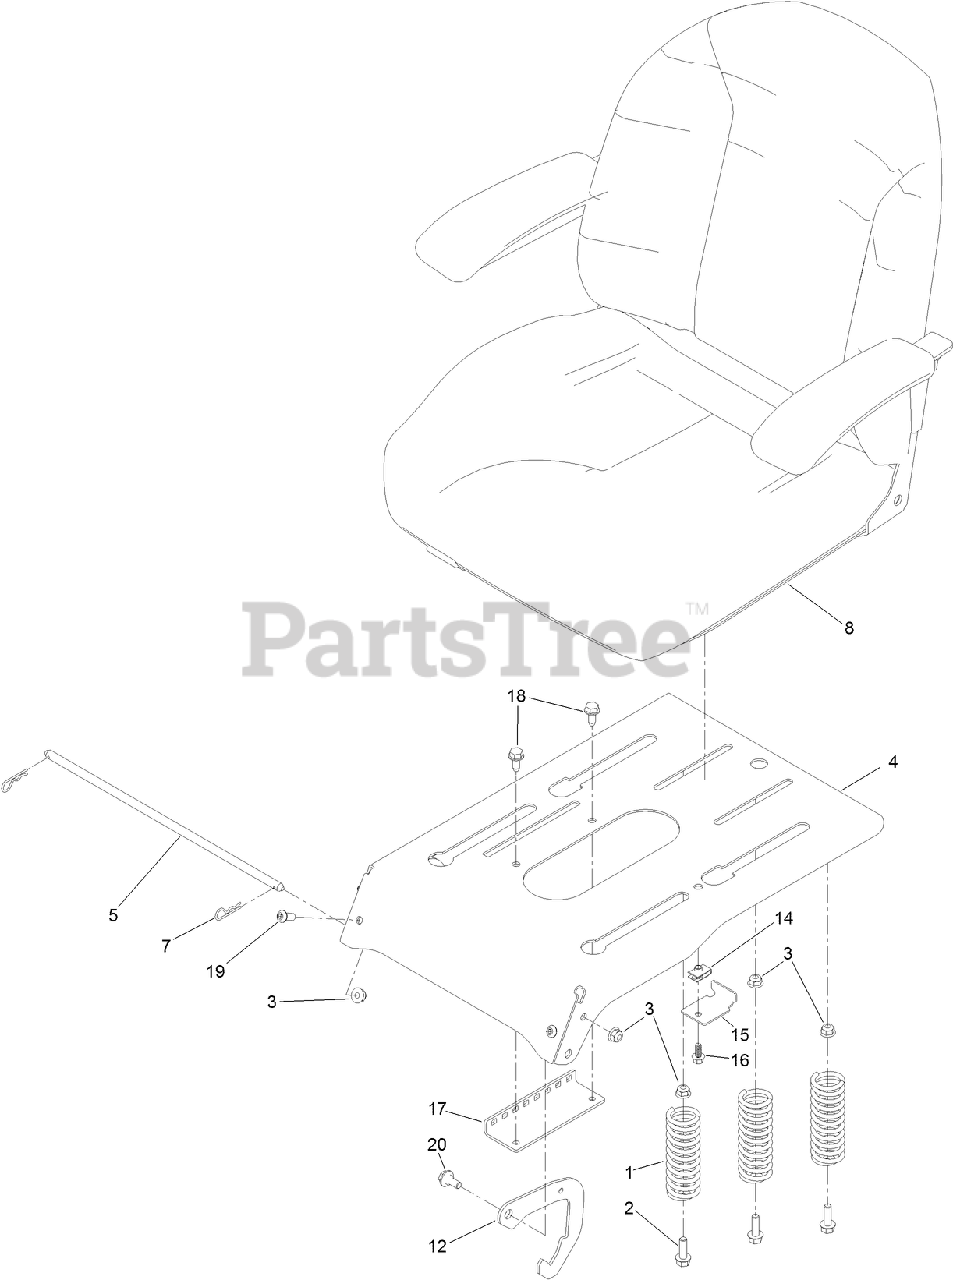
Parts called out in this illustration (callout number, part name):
1	SPRING-COMPRESSION
2	SCREW-HHF
3	NUT-HF, NI
4	PAN-SEAT, DELUXE
5	ROD-PIVOT, NARROW
7	PIN-COTTER
8	SEAT ASM
12	LATCH-SEAT
15	BRACKET-STOP, SEAT
16	SCREW-HHF
17	BRACKET-LATCH, SEAT
18	SCREW-HWHTF
19	SCREW-HSBH
20	SCREW-SHOULDER
